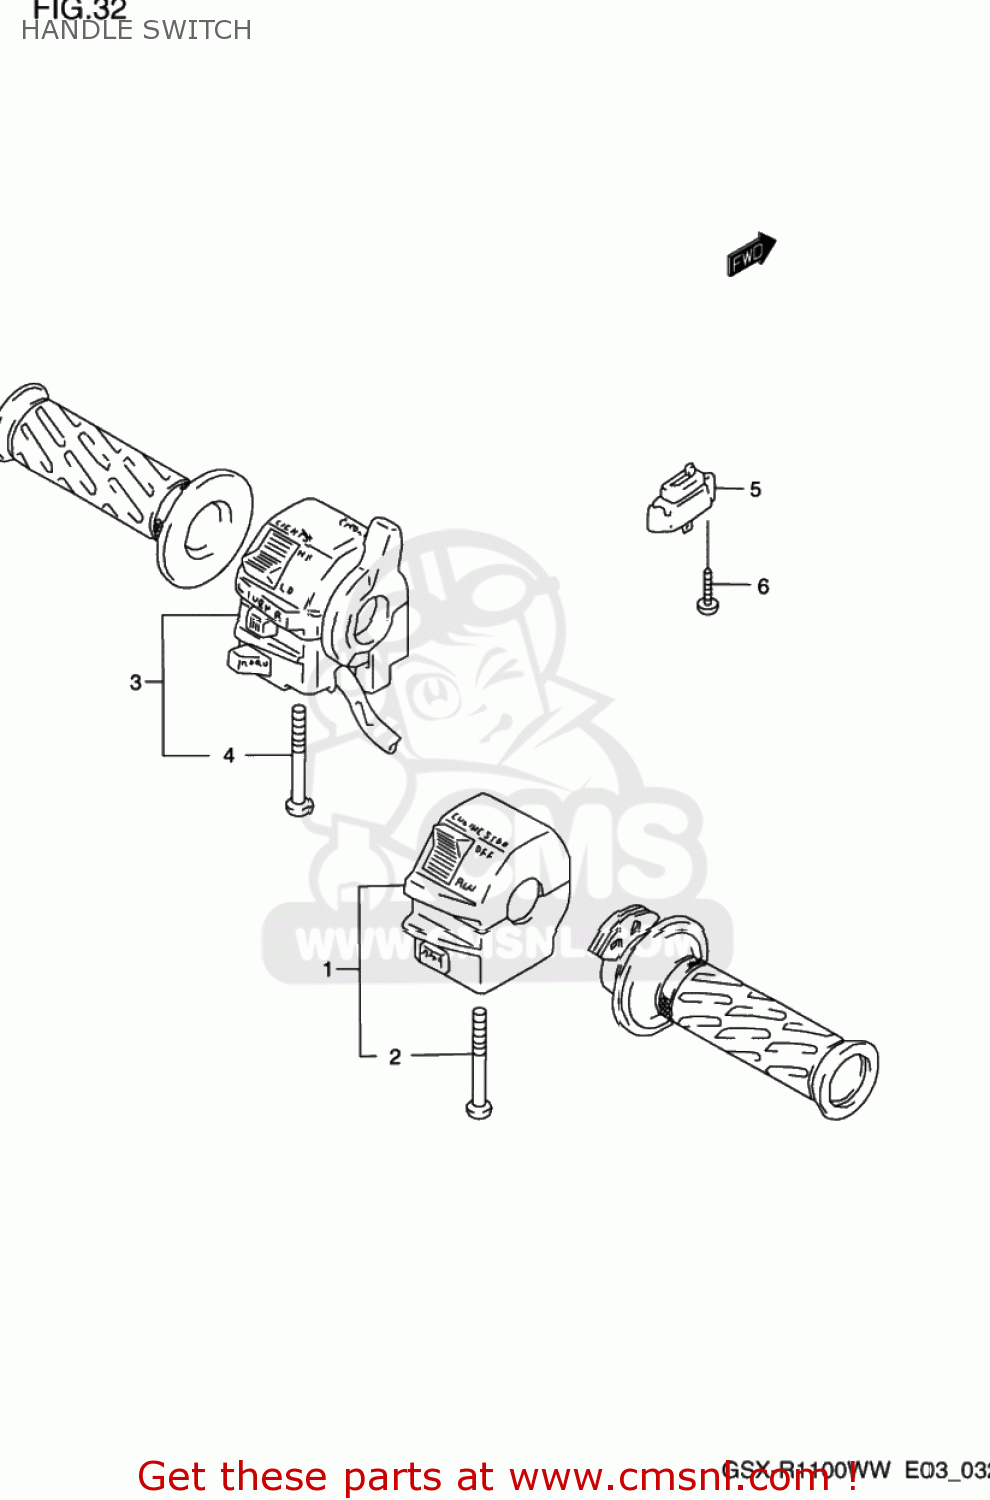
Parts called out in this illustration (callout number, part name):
1	SWITCH ASSEMBLY,HANDLE,RIGHT
2	SCREW, 5X45
3	SWITCH ASSY,HANDLE,L
4	SCREW, 5X45
5	SWITCH ASSY,CLUTCH
6	SCREW
